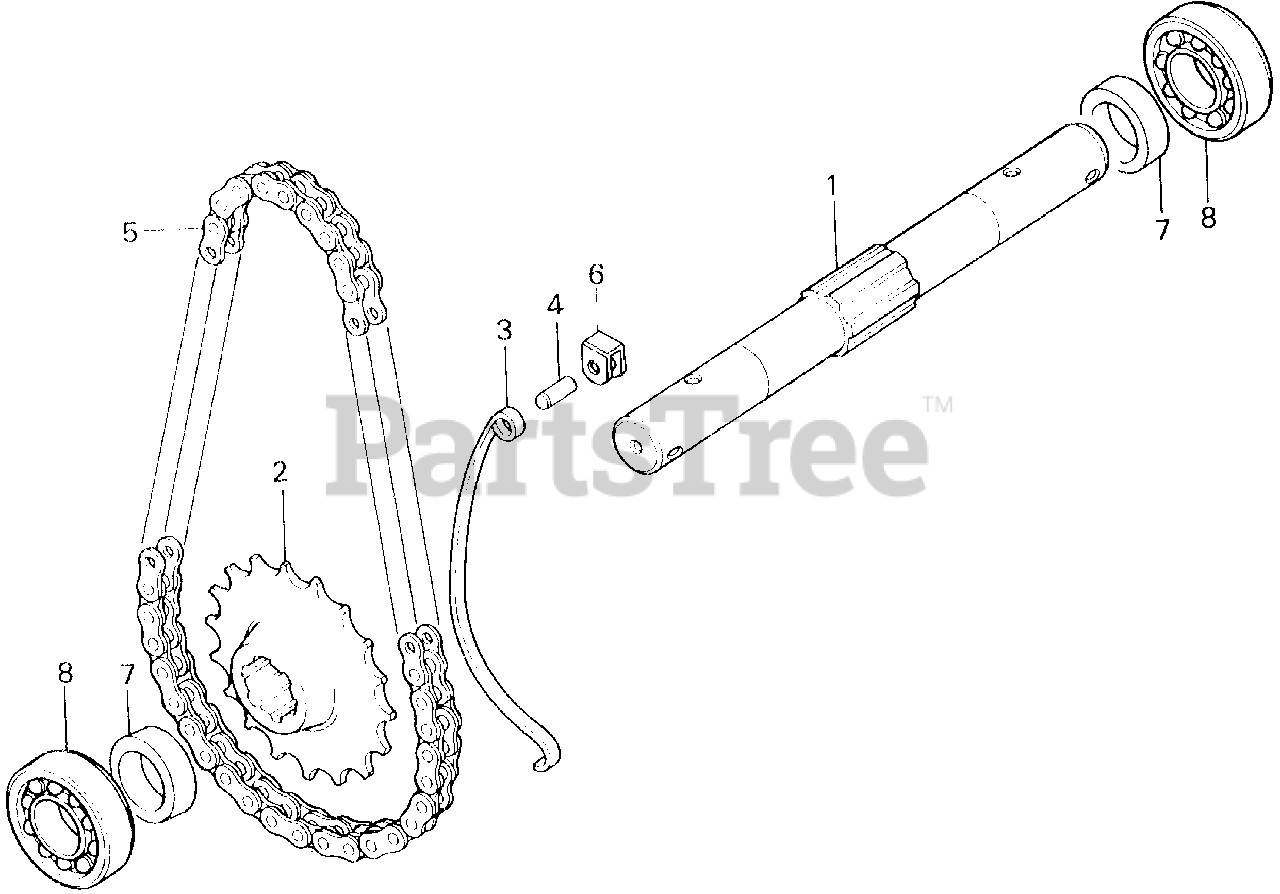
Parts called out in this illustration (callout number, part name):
1	SHAFT, WHEEL
2	SPROCKET, DRIVEN
3	TENSIONER, CHAIN (NOT AVAILABLE)
4	SHAFT, TENSIONER (NOT AVAILABLE)
4	SHAFT, TENSIONER
5	CHAIN, FINAL (RK520KFX44LE)
6	SPACER, CHAIN TENSIONER
7	COLLAR, WHEEL SHAFT
8	BEARING, RADIAL BALL (6007)
